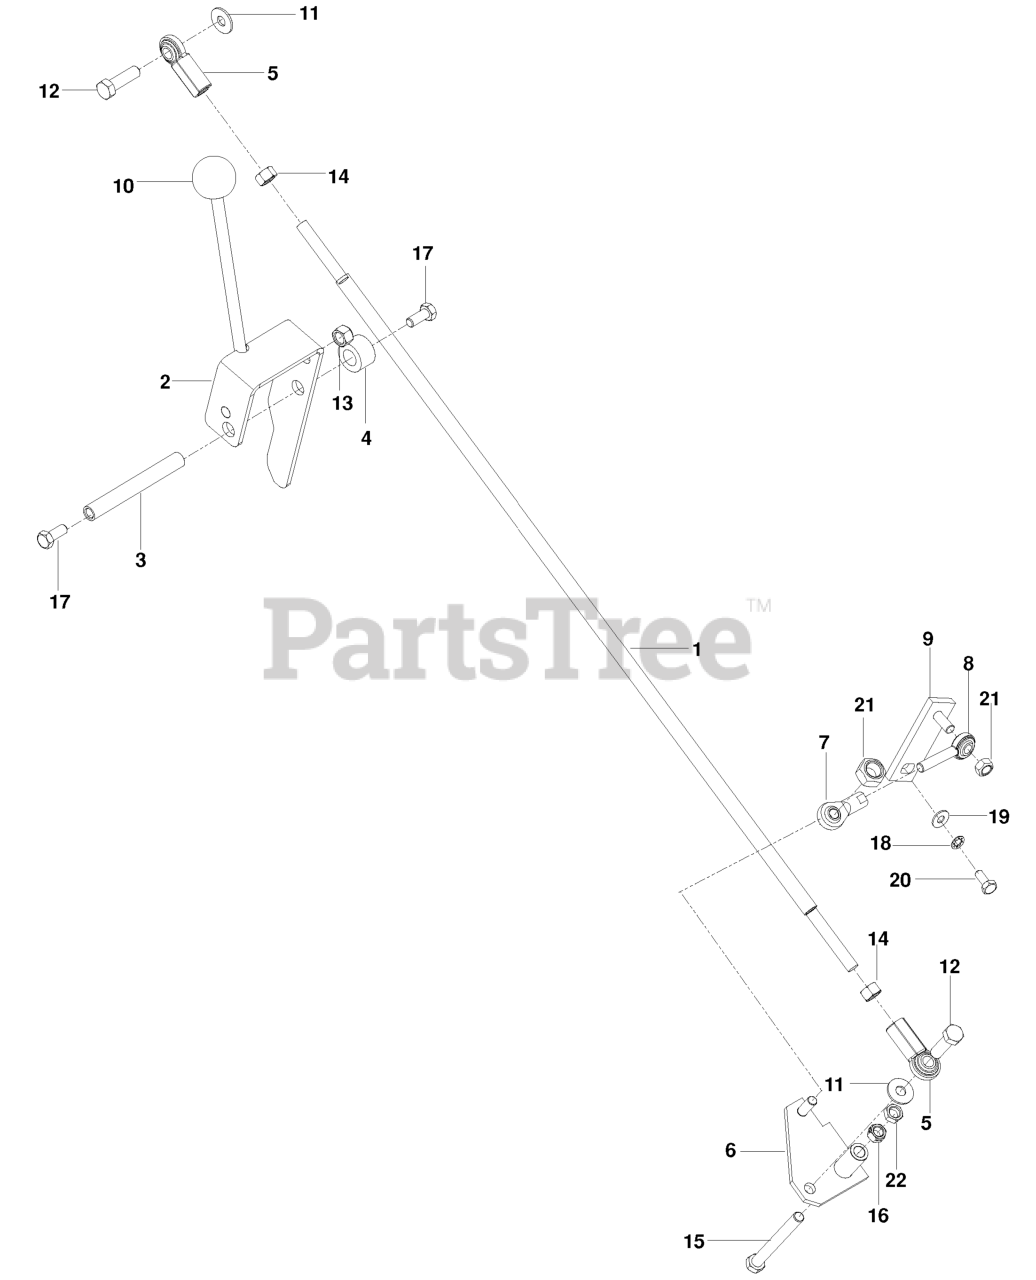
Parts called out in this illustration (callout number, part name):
1	SHIFT ROD, BLACK
2	SHIFT LEVER, ORANGE
3	SHAFT - SHIFT PIVOT
6	BELL CRANK SHIFT KIT
7	BALL JOINT, RIGHT HANDED
8	ROD END 5/16 MALE
9	KIT ARM TRANS SHIFT W/HDW
10	KNOB-SHIFT
11	WASHER 5/16 FLAT
12	HCS 3/8C X 1 1/4 GR5
13	NUT 3/8-16 NYLOC
15	HCS 3/8C X 3 1/2
16	NUT 3/8C CENTERBLOCK
17	HCS 5/16C X 3/4
18	WASHER 1/4 INT TOOTH
19	WASHER 1/4 SAE
20	HCS 1/4-28.X
21	NUT 5/16-24 TOP LK GRC ZD
22	NUT 3/8-16 HEX JAM
